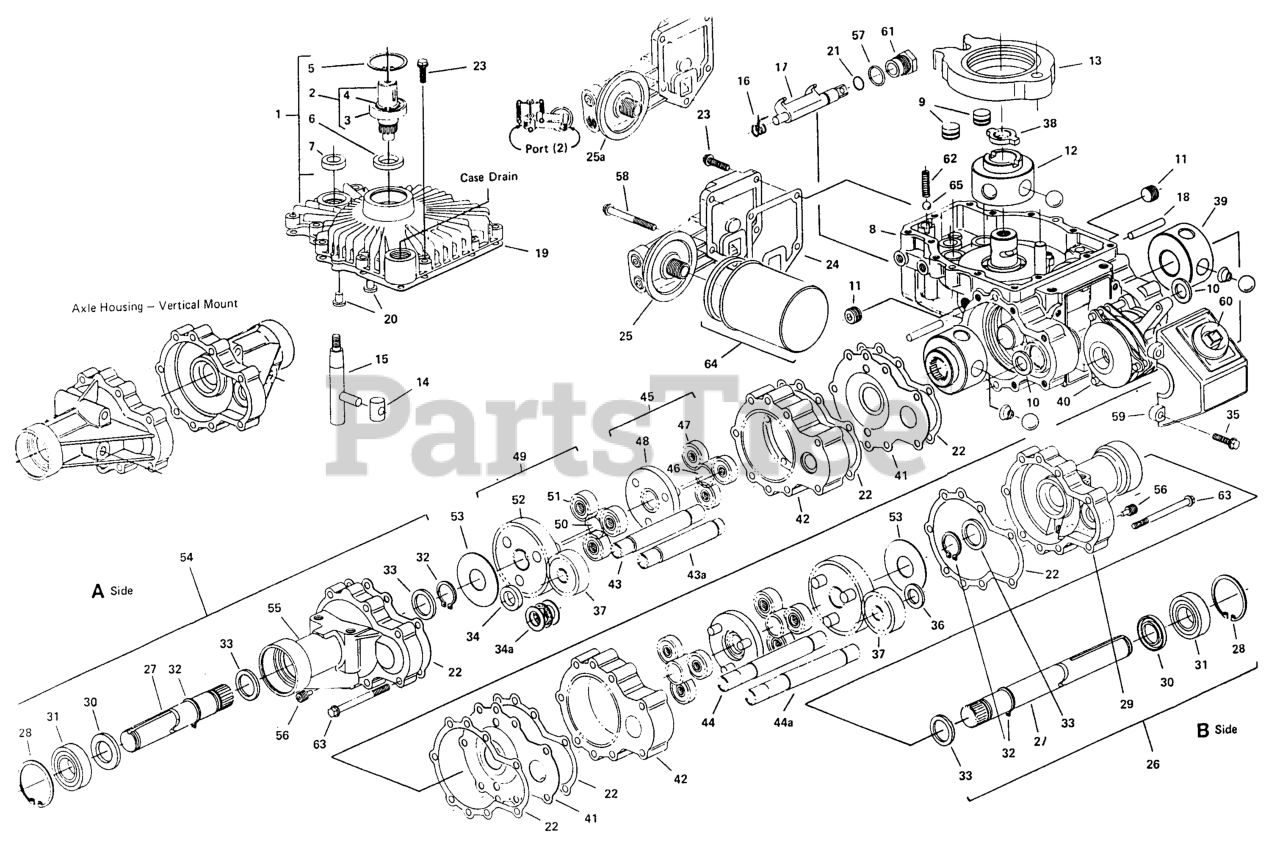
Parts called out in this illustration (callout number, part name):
1	Cover, Subassembly (S/A)
2	Shaft, Input, S/A
3	Bearing, Input Shaft
4	Ring, Retaining, External
5	Ring, Retaining, Internal
6	Seal, Input Shaft
7	Seal, Control Shaft
8	Housing, S/A
9	Piston, Dampening, S/A
10	Seal, Brake Shaft
11	Plug, Socket Pipe
12	Pump Rotor-Ball-Pin, S/A
13	Cam Ring, S/A
14	Insert
15	Control Shaft, S/A
16	Spring, Dump Valve
17	Bracket, Dump Valve
18	Dowel
19	Gasket, Cover
20	Button
21	O-Ring
22	Gasket, Axle Housing
23	Screw, 1/4-20 Hex Flanqe
24	Gasket, Filter Base Or Port Plate
25	Filter Base, S/A
26	Axle Housing, S/A - B
27	Shaft, Axle
28	Retaining Ring, Internal
29	Housing, Axle - B
30	Seal, Axle Shaft
31	Bearing, Axle
32	Retaining Ring, External
33	Washer, Thrust
34	Spacer (Thick- Pb)
34A	Washers, Thrust And Bearing, Thrust (Dl/Pb)
35	Screw, 1/4-20 Self Tap
36	Spacer (Thin- Pb Or Dl/Pb)
37	Brake Gear
38	Drive
39	Motor, Rotor-Ball, A & B S/A
40	Parking Brake Or Option Differential Lock/Parking Brake (Pb Or Dl/Pb
41	Plate, Wear
42	Ring Gear, A & B S/A
43	Brake Shaft-A (Pb)
43A	Brake Shaft-A (Dl/Pb)
44	Brake Shaft-B (Pb)
44A	Brake Shaft-B (Dl/Pb)
45	Planetary Gear, First, Subassembly
46	Sun Gear, First
47	Plnt Gear, First, A & B S/A
48	Primary Carrier, A & B S/A
49	Planetary Gear, Second, A & B S/A
50	Sun Gear, Second
51	Plnt Gear, Second, A & B S/A
52	Secondary Carrier, A & B S/A
53	Washer, Thrust
54	Axle Housing, S/A - A
55	Housing, Axle - A
56	Plug, Magnetic
57	O-Ring, Dump Valve Nut
58	Screw, 1/4-20 Hex Flange
59	Cover (Pb Or Dl/Pb)
60	Boot, Dust
61	Nut, Dump Valve
62	Spring, Relief Valve
63	Screw, 1/4-20 Hex Flange
64	Filter, Oil (W/Seal)
